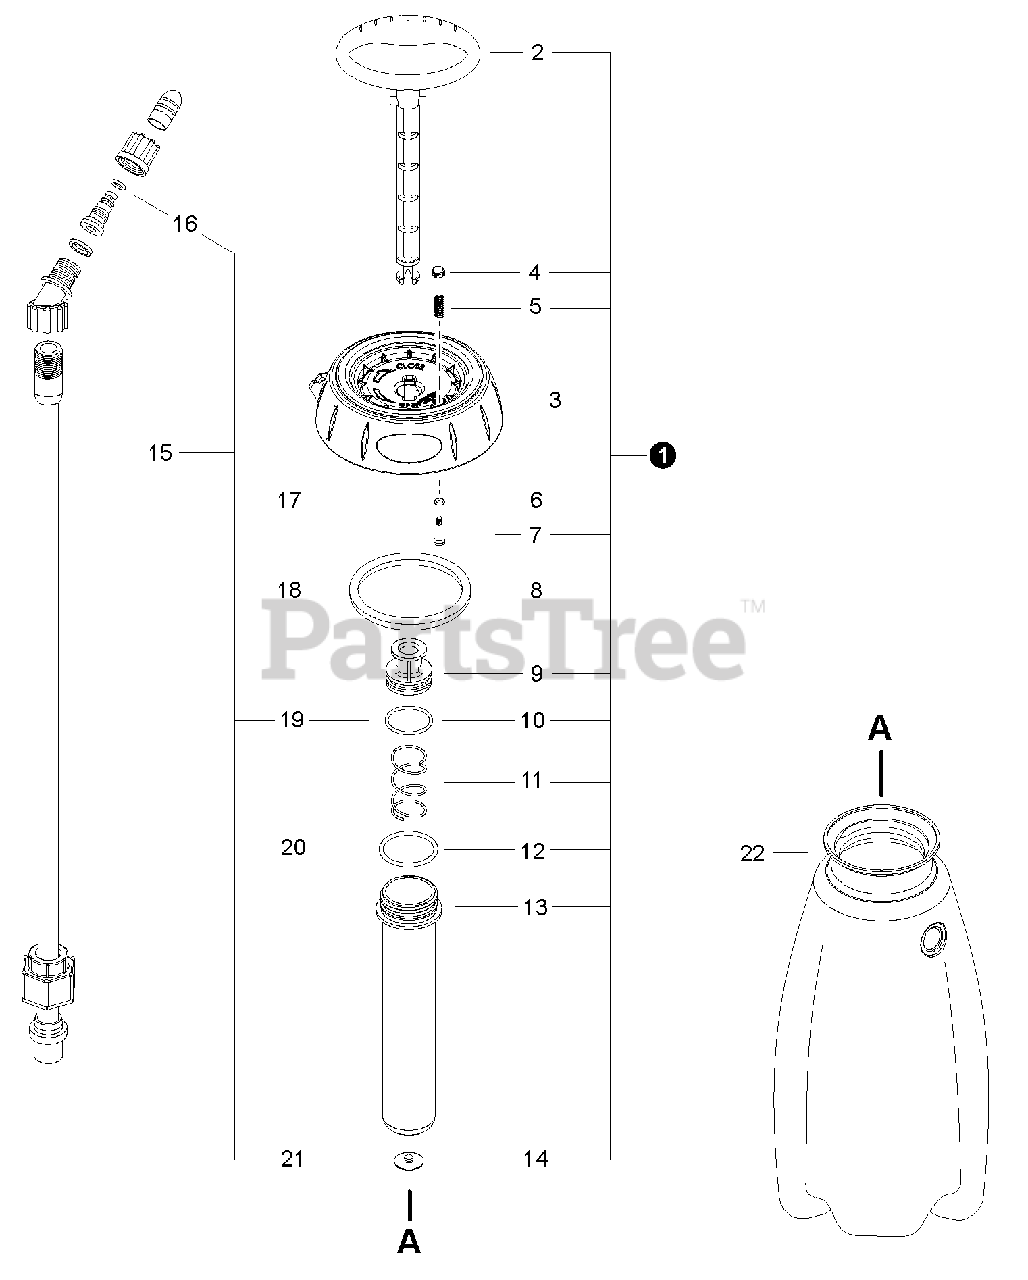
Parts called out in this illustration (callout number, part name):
1	PUMP ASSY
2	HANDLE, PUMP
3	CAP, TANK
4	BUTTON, PRESSURE RELIEF
5	SPRING, PRESSURE RELIEF
6	O-RING, PRESSURE RELIEF
7	VALVE, PRESSURE RELIEF
8	O-RING, CAP
9	PLUNGER, PUMP
10	O-RING, PLUNGER
11	SPRING, PUMP
12	O-RING, BARREL
13	BARREL, PUMP
14	VALVE, CHECK
15	REPAIR KIT, PUMP
16	O-RING, NOZZLE
17	O-RING, PRESSURE RELIEF
18	O-RING, CAP
19	O-RING, PLUNGER
20	O-RING, BARREL
21	VALVE, CHECK
22	TANK, SPRAYER
